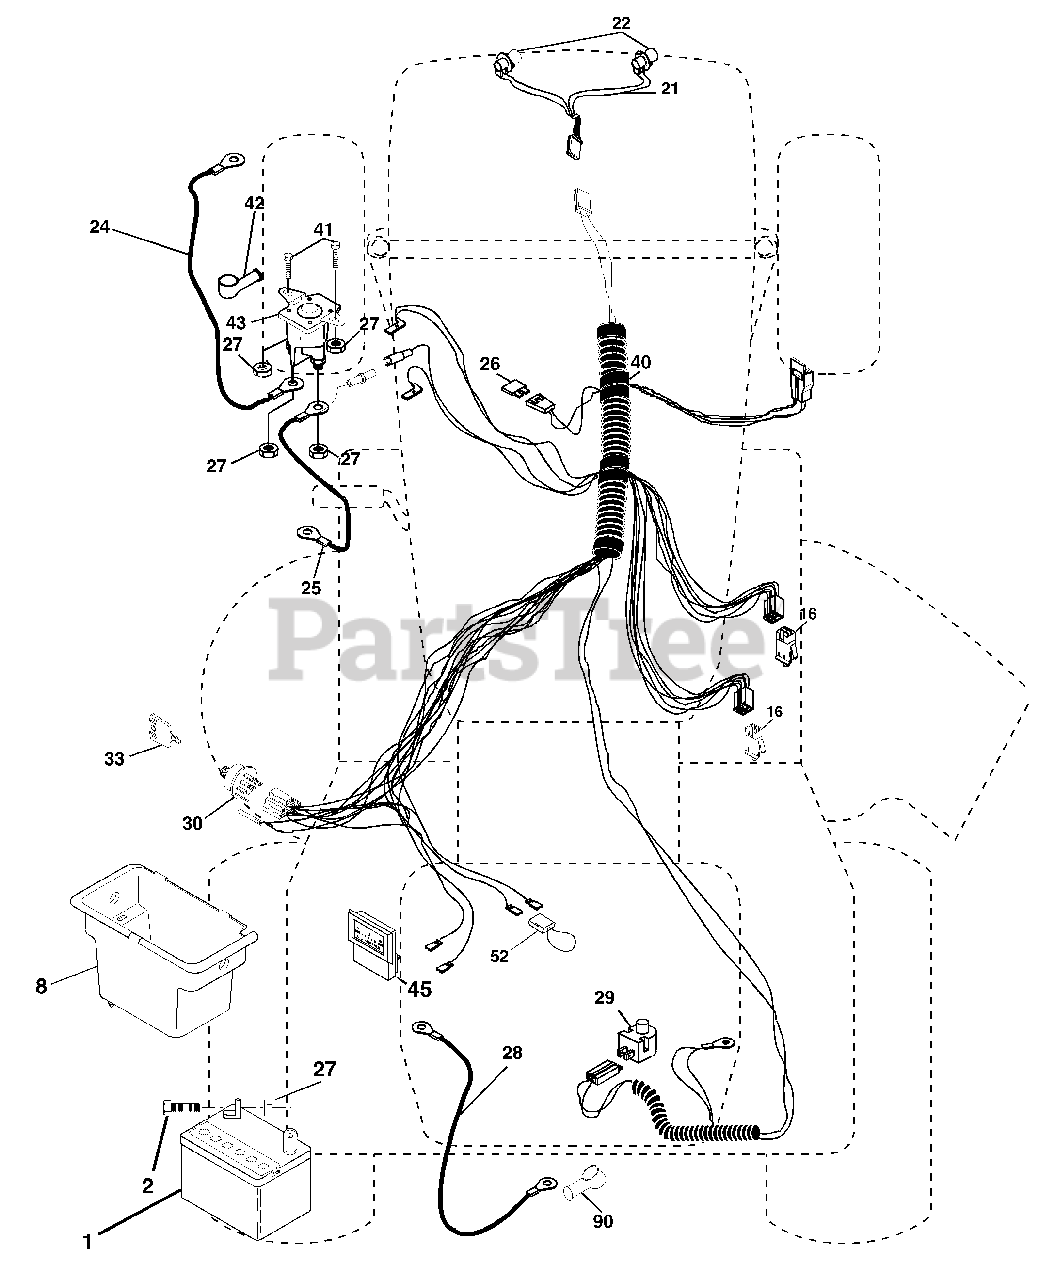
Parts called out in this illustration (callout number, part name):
1	Battery
2	Bolt Hex Hd 1/4-20 unc x 3/4
8	Box Battery
16	Switch Interlock
21	Harness Asm Light W/4152j
22	Bulb Light #1156
24	Cable Battery 6 Ga. 11" red
25	Cable Battery 6 Ga. 44" red w/16 wire
27	Nut Keps Hex 1/4-20 unc
28	Cable Ground 6 Ga 12" black
29	Switch Plunger Olive
30	Switch Ign Delta
33	Key Ign Molded Generic
40	Harness Ign.
41	Bolt Blk Fin Hex 1/4 - 20 x 1/2
42	Cover Terminal Red
43	Solenoid
45	Ammeter Rectangular
52	Protection Wire Loop
90	Cover Terminal Battery
